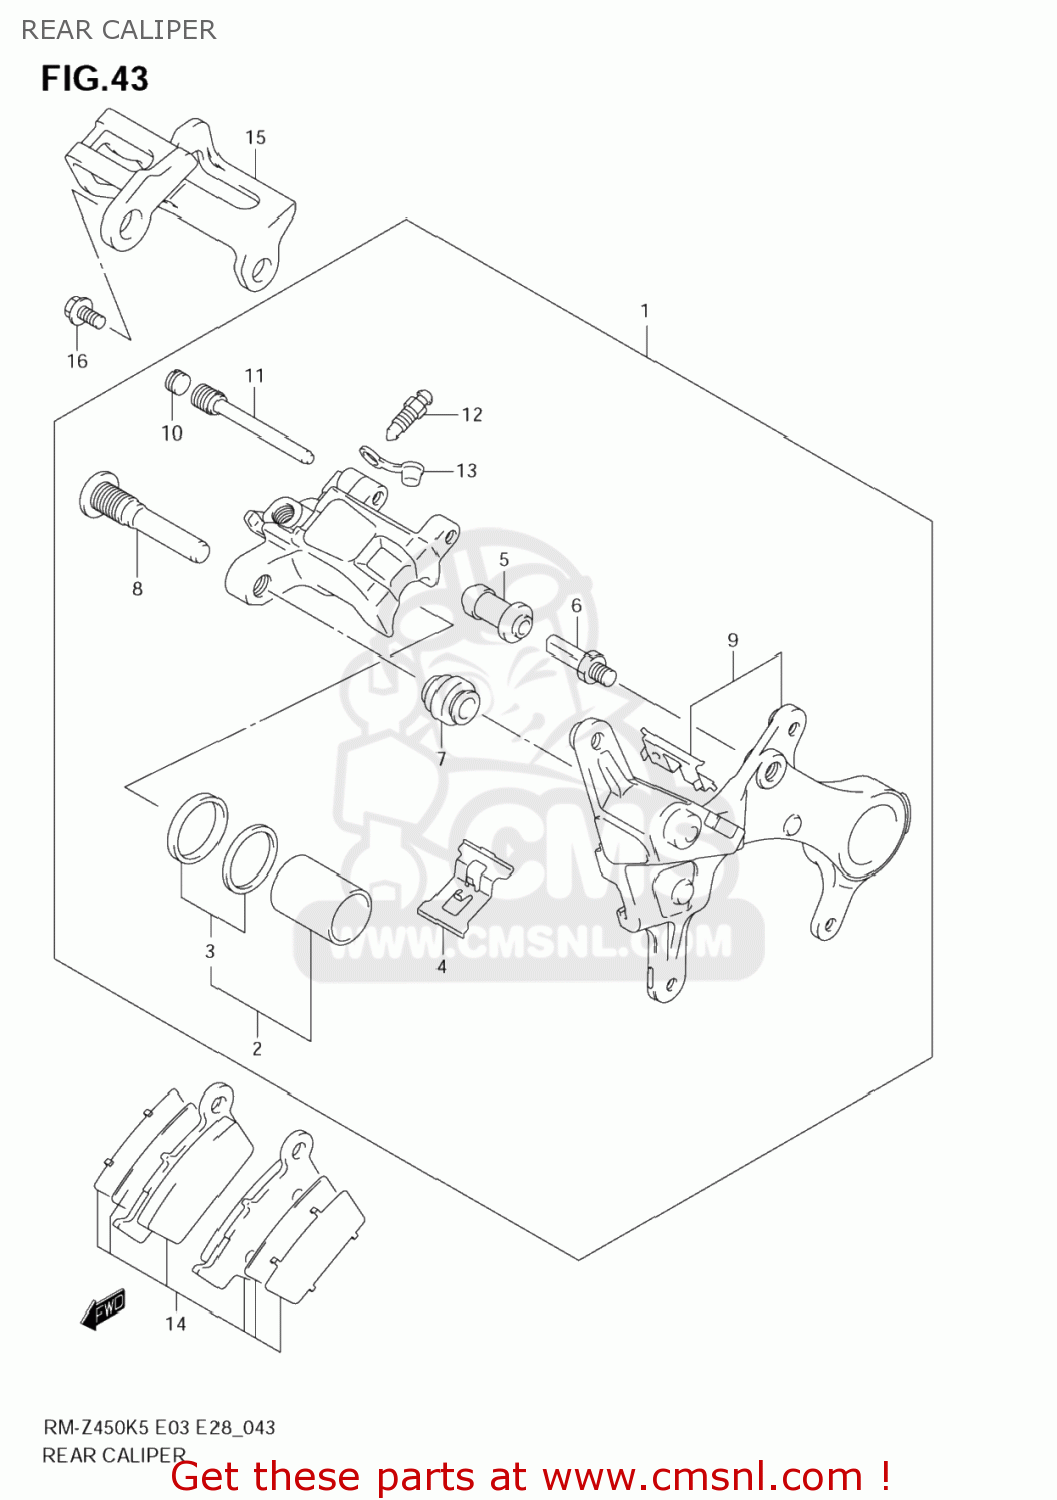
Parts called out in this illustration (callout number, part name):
1	CALIPER ASSY,RR
2	PISTON SET
3	SEAL SET,PISTON
4	SPRING,PAD
5	BOOT
6	BOLT
7	BOOT
8	PIN,BOLT
9	BRACKET
10	PLUG,PIN
11	PIN,HANGER
12	BLEEDER
13	CAP,BLEEDER
14	PAD & SHIM SET (NAS)
15	GUARD,RR CALIP
16	BOLT(6X12)
